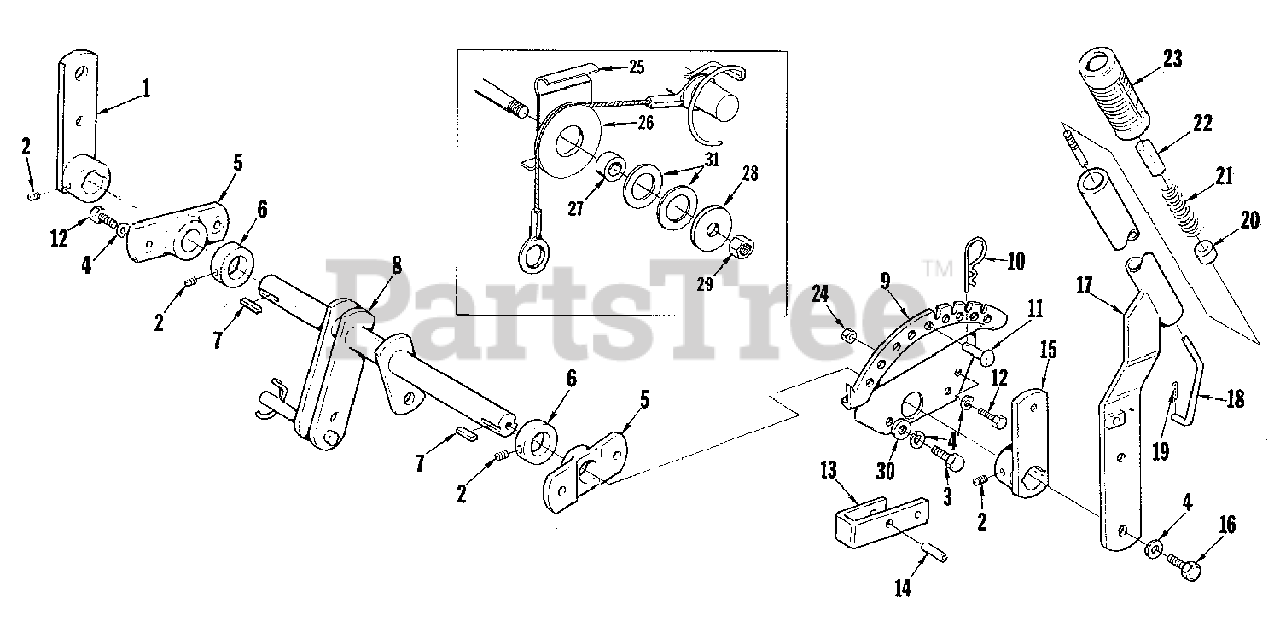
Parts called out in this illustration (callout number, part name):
1	LEVER ASSEMBLY, Front Lift
2	SETSCREW, Hex Socket, 5/16-18 x 5/16
3	SCREW, Hex Head Cap
4	WASHER, Lock
5	BEARING, Lift Lever
7	KEY, Plain Parallel
8	SHAFT ASSEMBLY, Lift
9	QUADRANT, Lift Lever
10	CLIP, Spring
12	SCREW, Hex Head Cap
13	LATCH, Lift Lever
15	LIFT LEVER ASSEMBLY, Inner Section
16	SCREW, Hex Head Cap, 3/8-16 x 1
17	LEVER ASSEMBLY, Lift
18	ROD, Latch Lift Lever
20	SPACER, Handle, Lift Lever
21	SPRING, Stand
22	BUTTON, Thumb
23	GRIP, Lift Lever
24	NUT, Hex Fin, 3/8-16
25	CLIP, Cable Retaining
27	SPACER, Pulley
28	WASHER, Flat, 13/32
29	NUT, Hex Lock, 3/8-16
30	WASHER, Flat, 3/8
